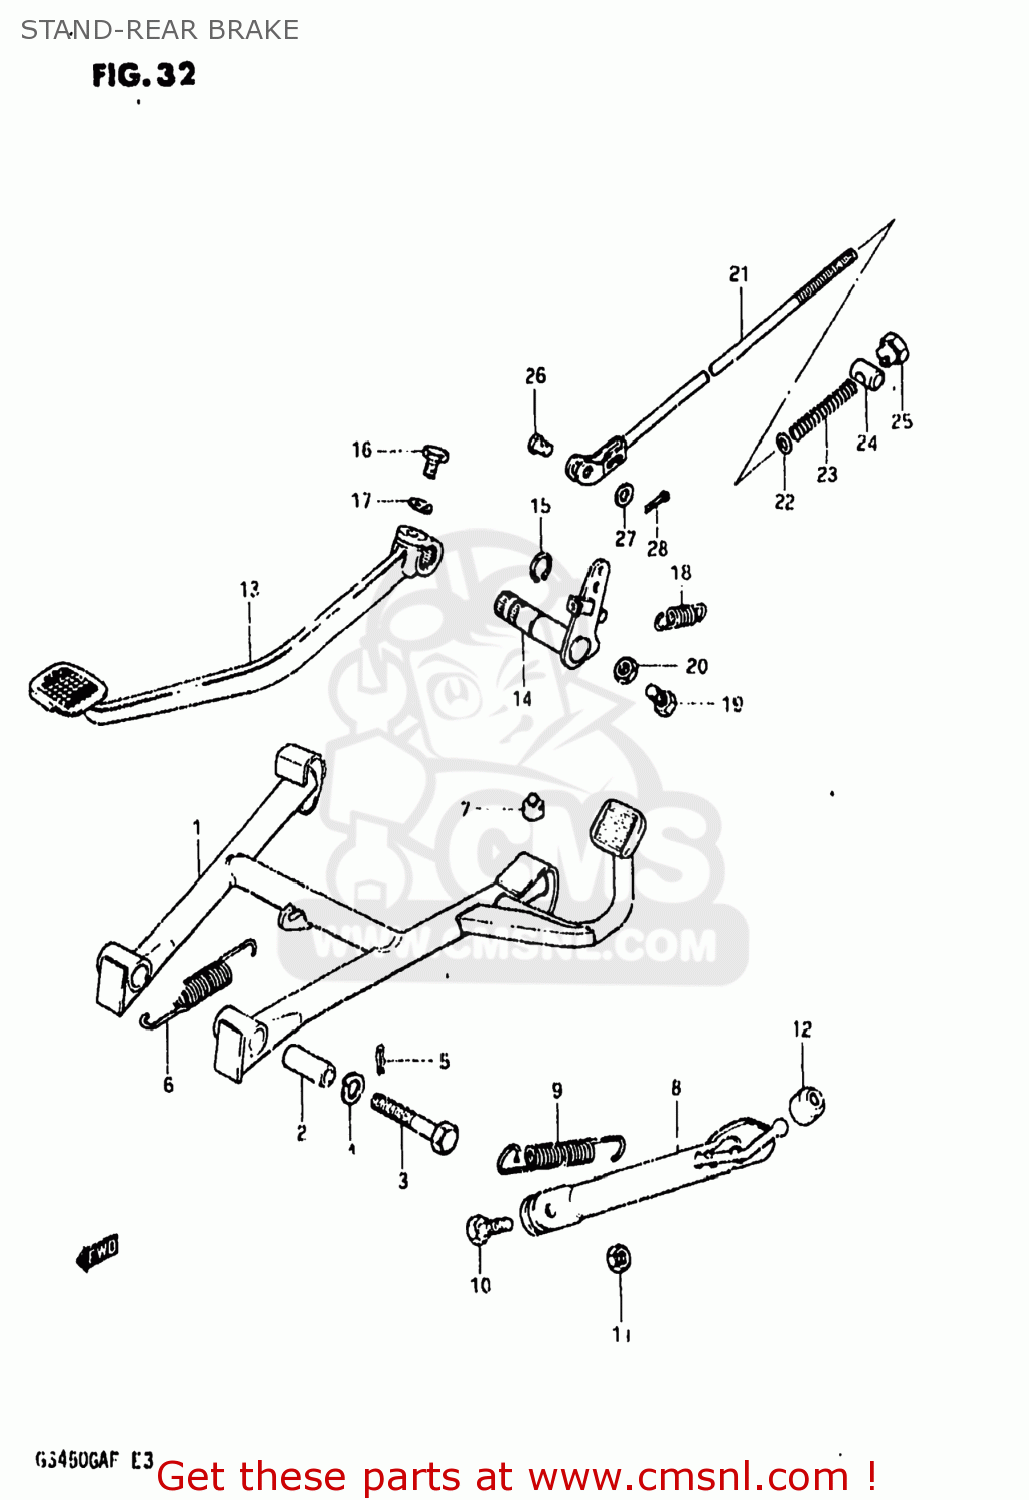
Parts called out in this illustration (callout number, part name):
1	STAND,CENTER
2	SPACER(10X16X38.8)
3	BOLT
4	LOCK WASHER
5	CLIP
6	SPRING
7	CUSHION
8	STAND,SIDE
9	SPRING
10	BOLT(10X30)
11	NUTM10X1.25X8
12	CUSHION
13	PEDAL,BRAKE
14	ARM,BRAKE PEDAL
15	CIRCLIP
16	BOLT
17	LOCK WASHER
18	SPRING
19	BOLT
20	NUT
21	ROD ASSEMBLY,REAR BRAKE
22	WASHER
23	SPRING
24	PIN
25	NUT (6MM)
26	PIN(L:13.5)
27	WASHER
28	PIN 20X20
